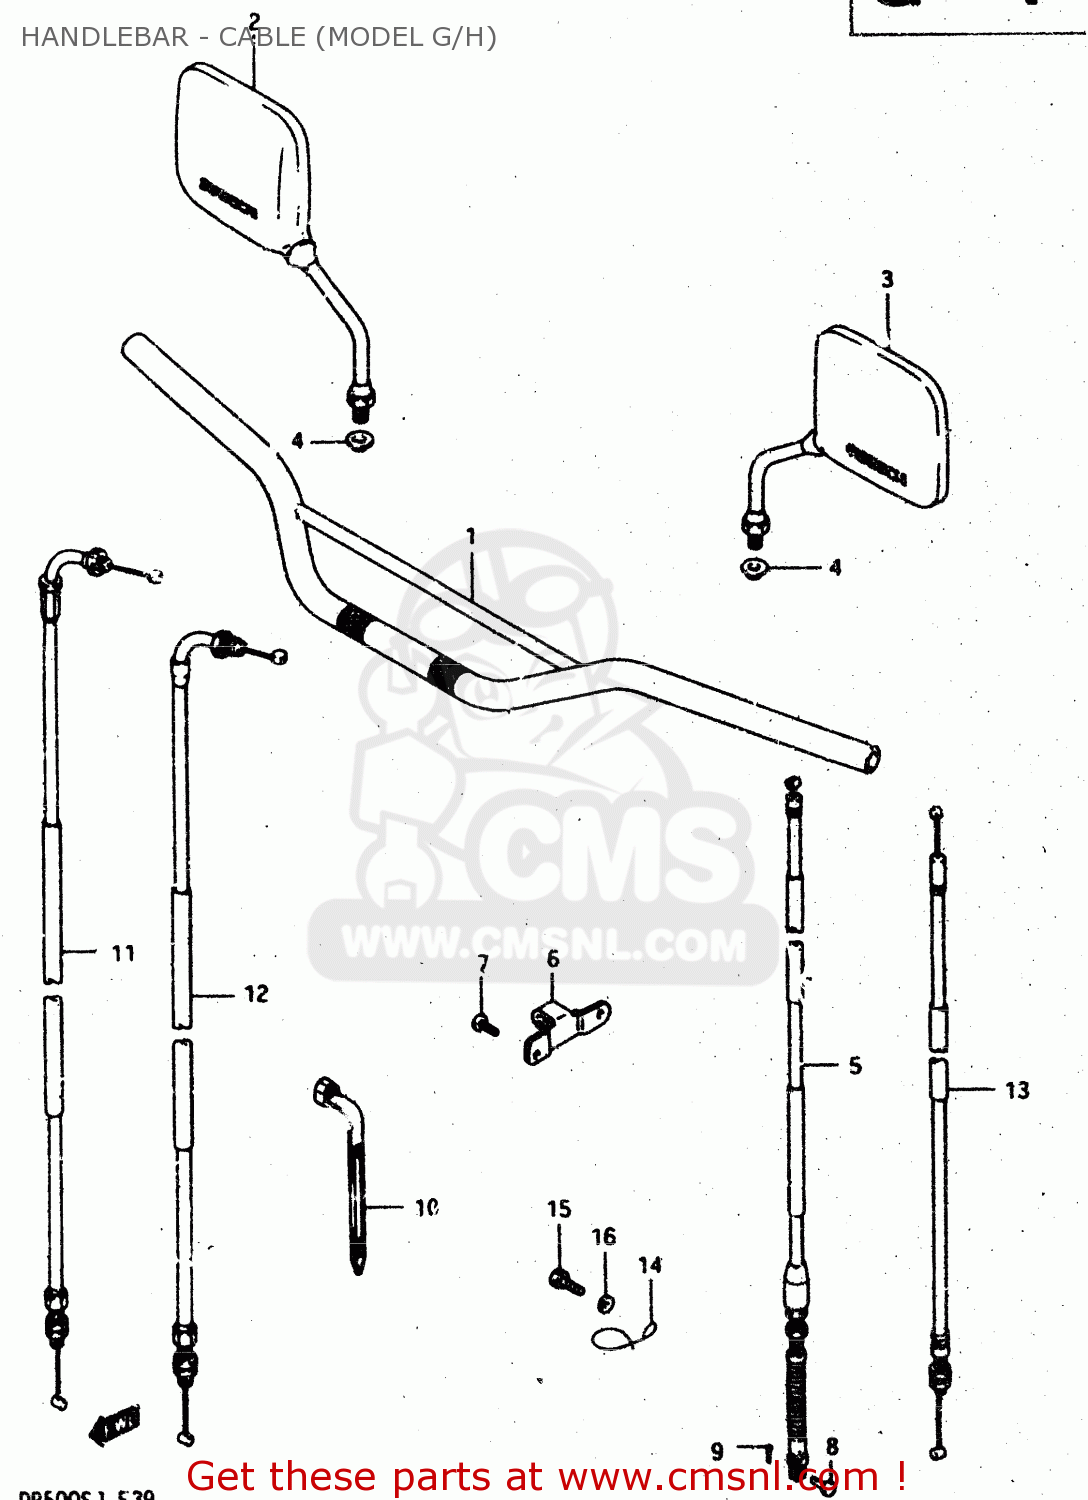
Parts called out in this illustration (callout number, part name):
1	HANDLEBAR
2	MIRROR ASSEMBLY,REAR VIEW
3	MIRROR ASSEMBLY,LEFT
4	WASHER
5	CABLE ASSY,CLUTCH
6	STOPPER,CLUTCH CABLE
7	SCREW
8	PIN(L:13)
9	PIN
10	CLAMP(L:125)
11	CABLE ASSY,THROTTLE NO.1
12	CABLE ASSY,THROTTLE NO.2
13	CABLE ASSY,DECOMP
14	GUIDE
15	BOLT
16	WASHER,LOCK
